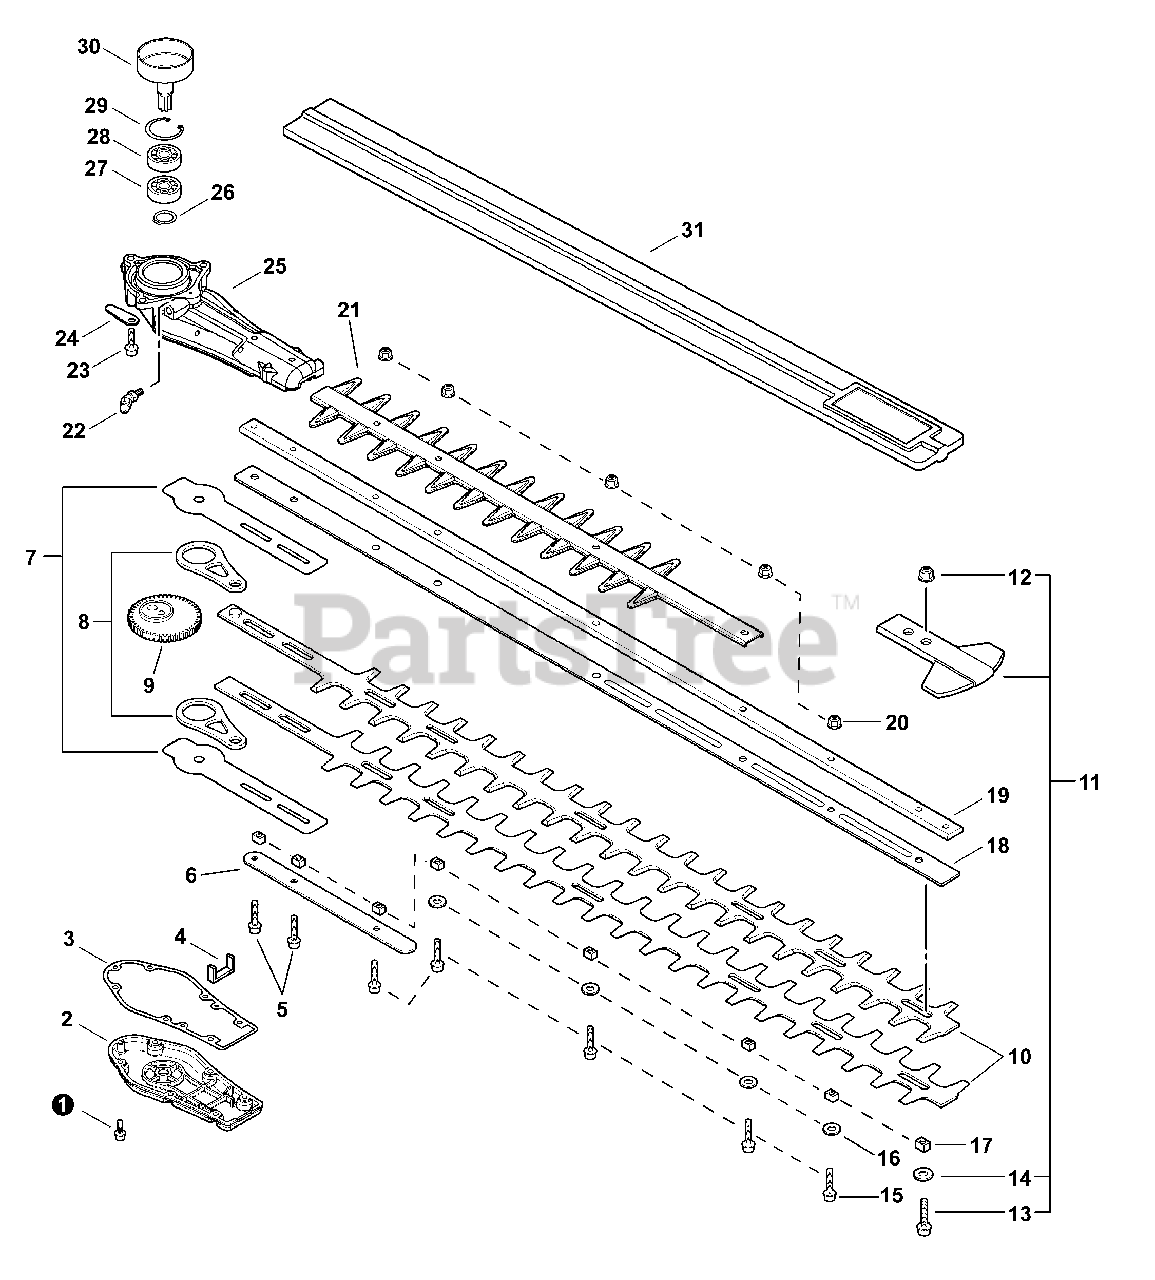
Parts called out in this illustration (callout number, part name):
1	SCREW - 4×16
2	LID, GEAR CASE
3	GASKET, GEAR CASE
5	SCREW - 5×25
6	SUPPORT, BLADE
7	PLATE, WEAR
8	ROD, CONNECTING
9	GEAR, SPUR
10	BLADE, TRIMMER
11	TIP GUARD KIT
12	LOCKNUT - 5
13	SCREW - 5×22
14	WASHER - 6
15	SCREW - 5×22
16	WASHER - 6
17	GUIDE, BLADE
18	SUPPORT, BLADE
19	SUPPORT, BLADE
20	LOCKNUT - 5
22	FITTING, GREASE
23	SCREW - 6×20
25	CASE, GEAR
26	RING, RETAINING - 14
27	BEARING, BALL - 6202
28	BEARING, BALL - 6202
29	RING, RETAINING - 35
30	DRUM, CLUTCH
31	COVER, BLADE
